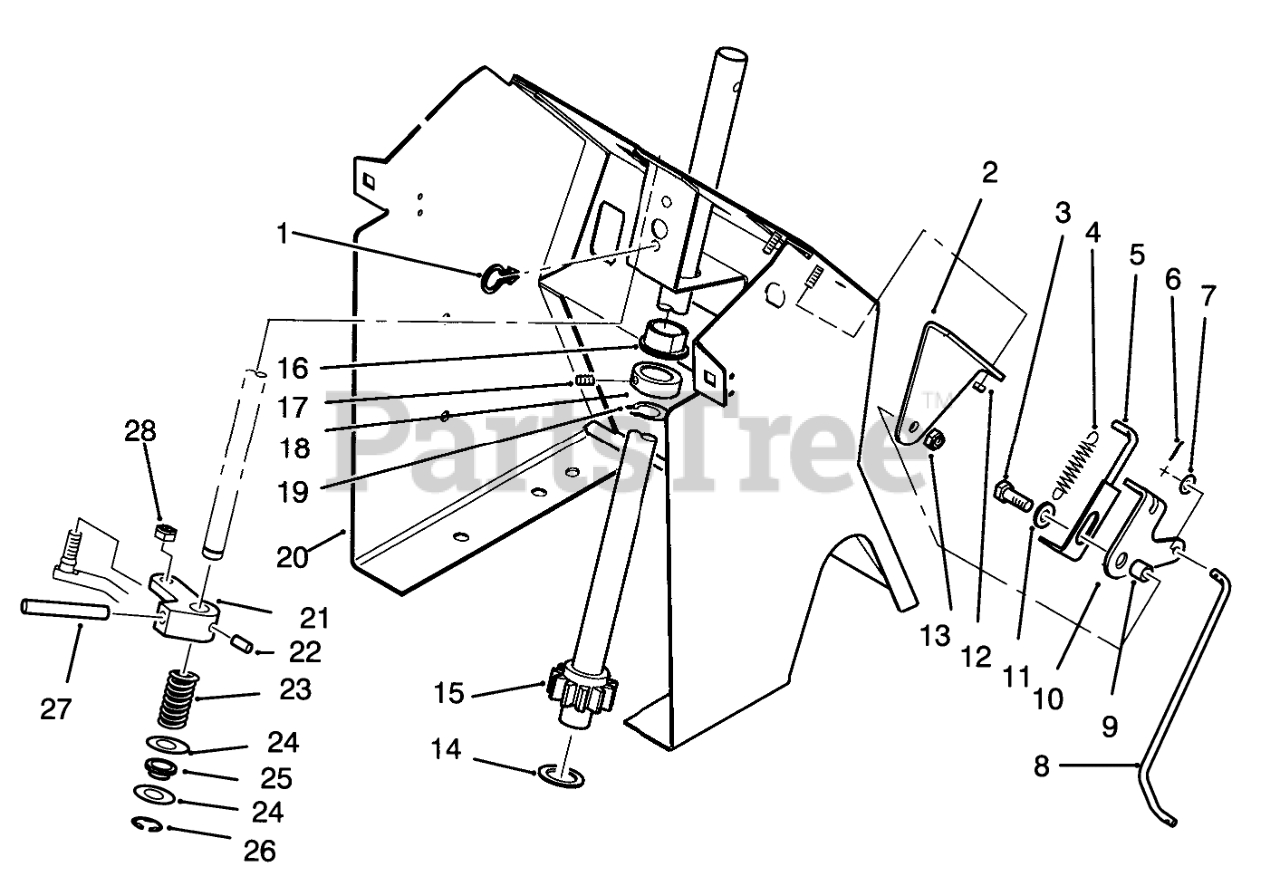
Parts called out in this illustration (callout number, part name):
1	CLIP-SNAP IN
2	SUPPORT-INDICATOR B
3	Bolt
4	SPRING-EXTENSION
5	WLDMT-INDICATOR R
6	Cotter Pin
7	WASHER-PLAIN
8	ROD-INDICATOR
9	SPACER
10	RETAINER-INDICATO B
11	WASHER-FLAT
12	Nut
13	NUT-LOCK, NI
14	WASHER
15	WLDMT-STRG SHAFT
16	BEARING-FLANGED
17	SCREW-HSH
18	COLLAR
19	RING-RETAINING
20	Hood Stand W.A.
21	ARM-SPEED CONTROL
22	PIN-SPIROL
23	SPRING-COMPRESSION
24	SHIM-WASHER
25	BUSHING-NYLINER
26	RING-SHAFT, EXT
27	PIN-SPIROL 5/16X2.25
28	NUT-LOCK
